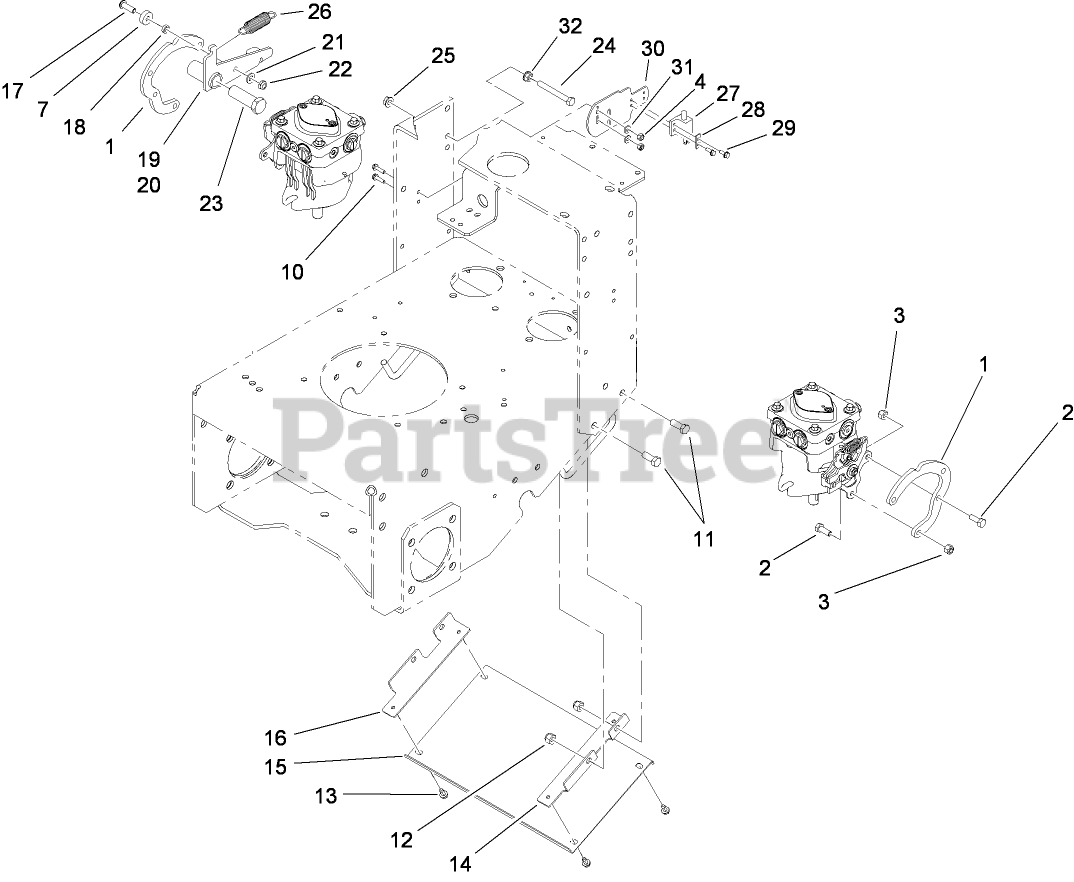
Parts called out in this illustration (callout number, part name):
1	BRACKET-ADAPTER, PUMP
2	SCREW-HH
3	NUT-LOCK, NI
4	NUT-LOCK, NI
7	BEARING-BALL
10	SCREW-HWH
11	SCREW-HH
12	NUT-LOCK, NI
13	SCREW
14	ANGLE-MOUNTING, LEFT
15	PANEL-BOTTOM
16	ANGLE-MOUNTING, RIGHT
17	SCREW-HSBH
18	SPACER-BEARING
19	RH DETENT ARM ASM
20	LH DETENT ARM ASM
21	WASHER-PLAIN
22	NUT-LOCK, NI
23	PIN-ADJUSTMENT, NEUTRAL
24	SCREW-HH
25	NUT-HF
26	SPRING-EXTENSION
27	SWITCH-CLOSED, NORMALLY
28	PLATE-SWITCH
29	SCREW-TAPTITE
30	BRACKET-NEUTRAL
31	WASHER-FLAT
32	NUT-HHF, SMOOTH
